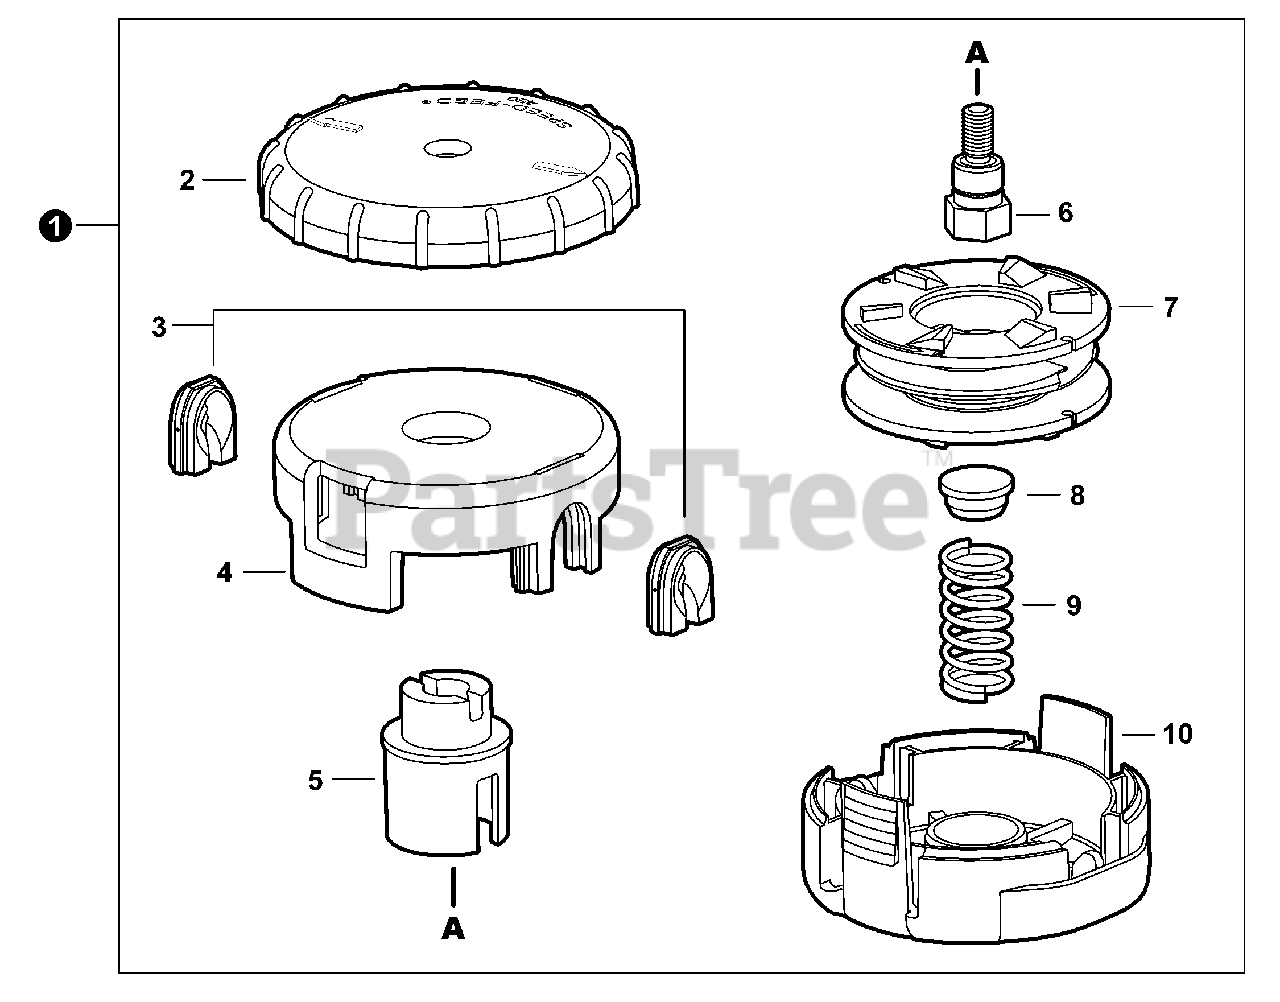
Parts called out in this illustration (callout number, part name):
1	TRIMMER HEAD, SPEED-FEED 450
4	HOUSING, SPOOL
5	HUB, SPOOL
6	BOLT, ARBOR 8MM×1.25 LH
7	SPOOL LH
8	CAP, SPRING
9	SPRING, COMPRESSION
10	COVER, SPOOL
